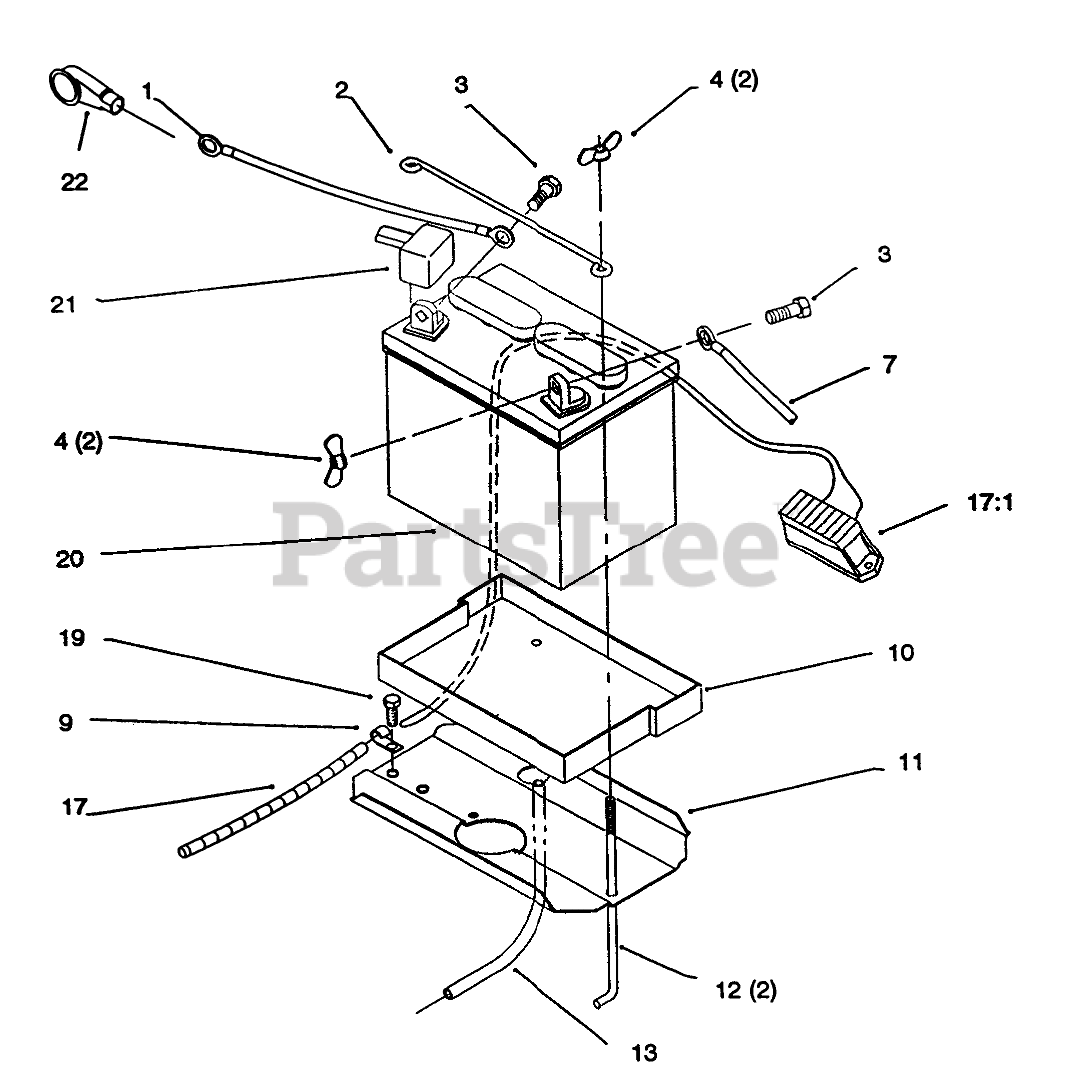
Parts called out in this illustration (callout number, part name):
1	Cable-Battery Red (Only On: 72103, 72083)
1	Cable-Battery Red (Only On: 72043, 72042, 72063, 72062)
2	ROD-BATTERY HOLD DWN
3	SCREW-HH
4	NUT-WING
7	Cable-Battery Black (Only On: 72043, 72042, 72063, 72062)
7	Cable-Battery Black (Only On: 72103, 72083)
9	CLIP
10	TRAY-BATTERY
11	PLATE-BATTERY
13	TUBE-21" BATTERY DRAIN
17	Harness-Wire (Only On: 72083, 72103)
17	Harness-Wire (Only On: 72043, 72063)
17	Harness-Wire (Only On: 72042, 72062)
17:1	FUSE-HOLDER 4 WAY
19	SCREW-HWHTF
20	Battery (Only On: 72042, 72062, 72043, 72063)
20	Battery (Only On: 72103, 72083)
21	Boot
22	Boot-Terminal Insulator (Only On: 72103, 72083)
